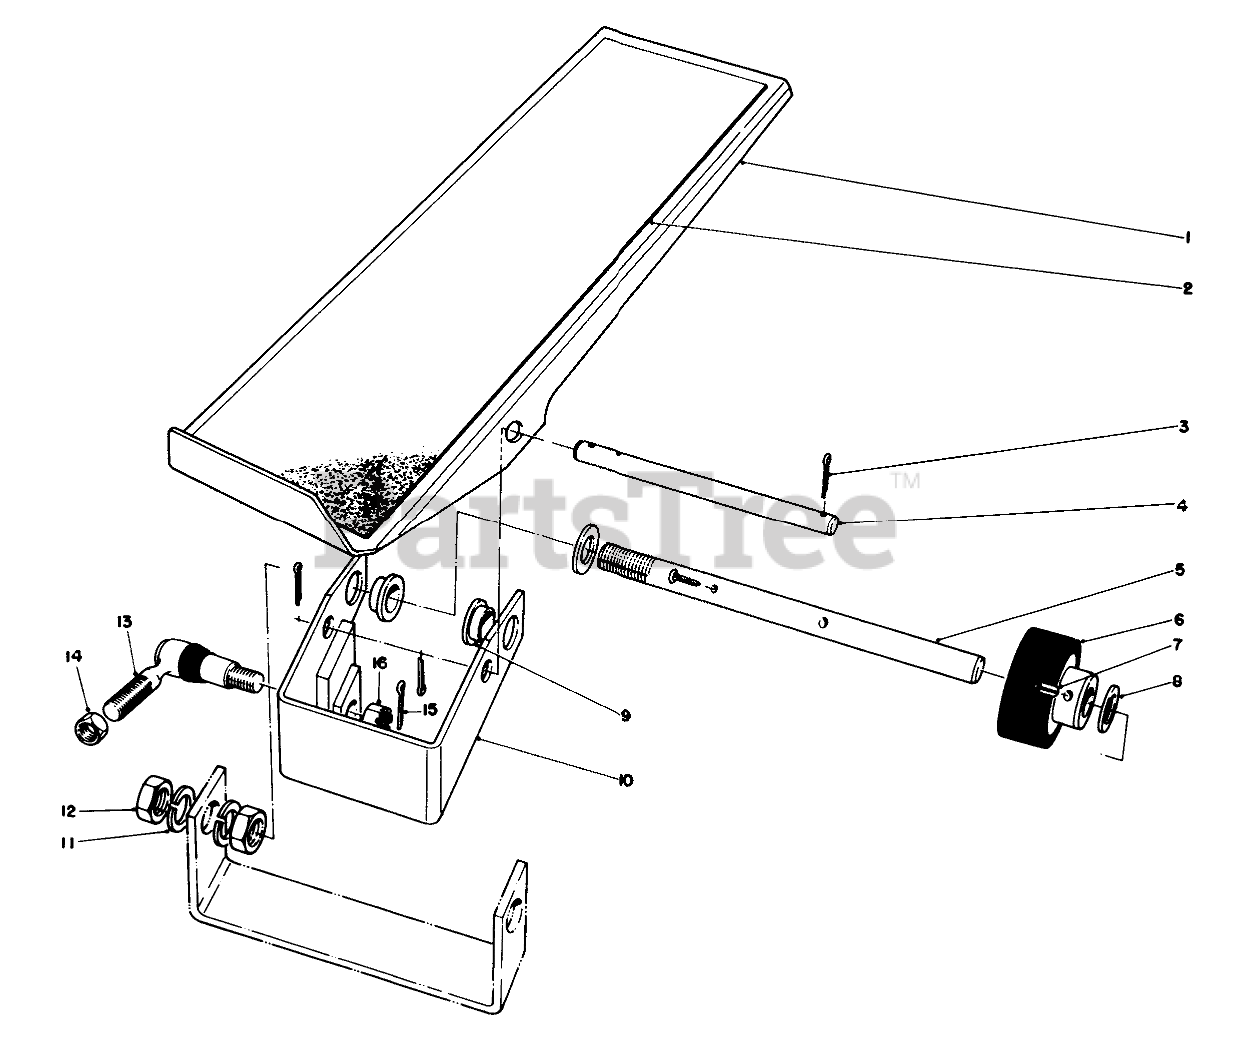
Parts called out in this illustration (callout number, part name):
1	Pedal-Traction
2	TRACTION PEDAL PAD
3	PIN-COTTER
4	PEDAL PIVOT PIN
5	Shaft-Traction Pedal
6	FRICTION WHEEL ASM
7	PIN-SPRING
8	WASHER-FLAT
9	BUSHING-FLANGE
10	Pivot Bracket Assembly (Incl. Ref. #9)
11	WASHER-LOCK
12	NUT-JAM
13	Socket Assembly R.H. (Incl. Ref. #16)
14	NUT-JAM
15	PIN-COTTER
16	NUT-SLOTTED
